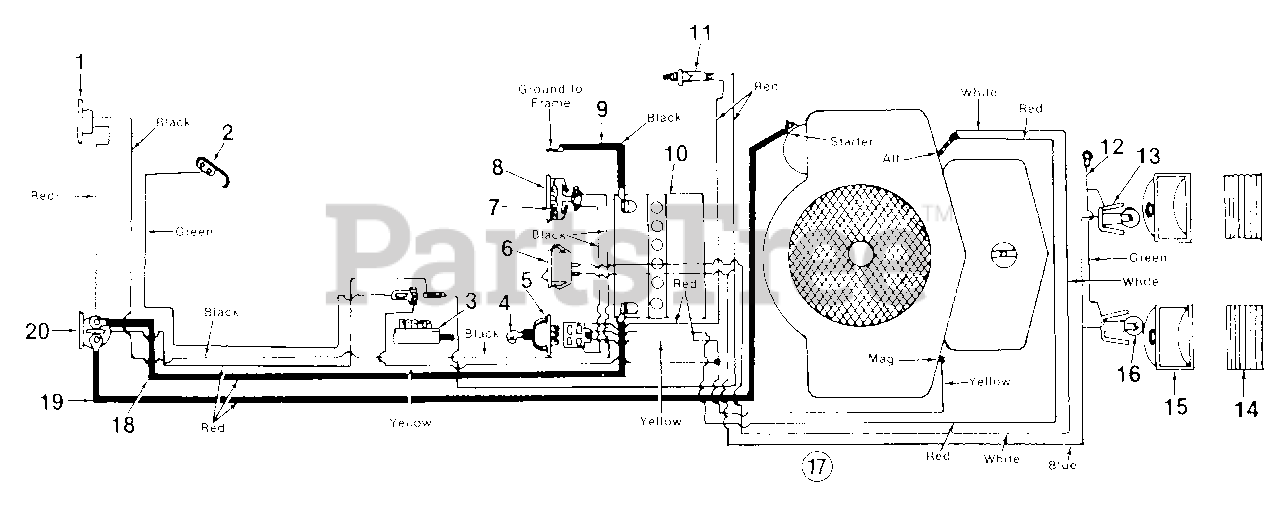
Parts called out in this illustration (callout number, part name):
1	Circuit Breaker
2	Spring Switch
3	Safety Switch Dpst.
4	Ignition Key
5	Ignition Switch
6	Headlight Switch
7	Foam Strip
8	Ammeter
9	Ground Wire 14.0" Lg.
10	12 Volt Battery
11	Safety Switch
12	Ground Wire
13	Socket
14	Lens
15	Headlight Housing
16	Lam p
17	Wire Harness
18	Electric Wire 27.0" Lg.
19	Electric Wire 32.5" Lg.
20	Solenoid
